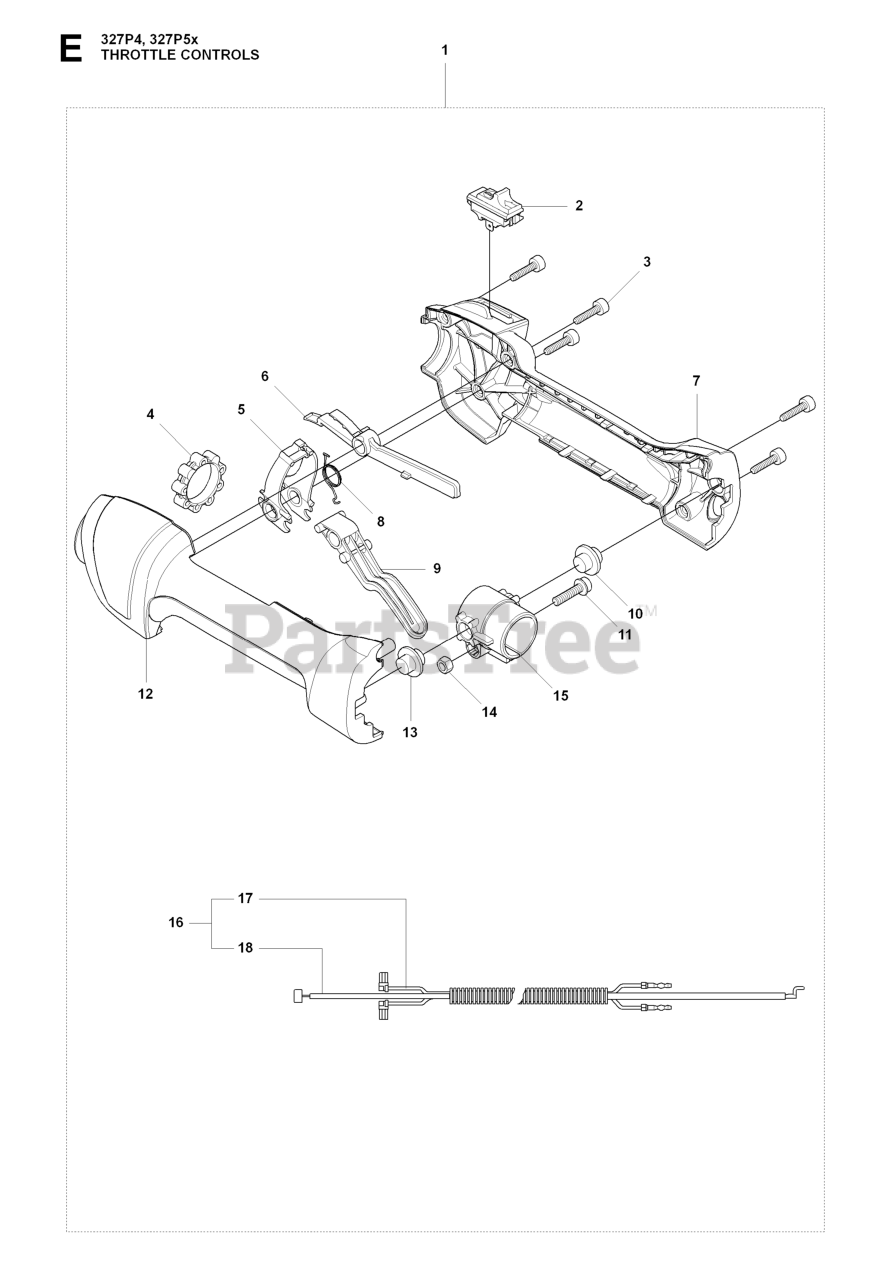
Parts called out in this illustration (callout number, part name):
1	ASSY THROTTLE CONTROL
2	STOP BUTTON
4	VIBRATION DAMPER
6	THROTTLE LOCK
8	RETURN SPRING
9	THROTTLE TRIGGER
10	VIBRATION ABSORBER
13	VIBRATION ABSORBER
17	SHORT CIRCUIT CABLE
18	THROTTLE WIRE ASSY
